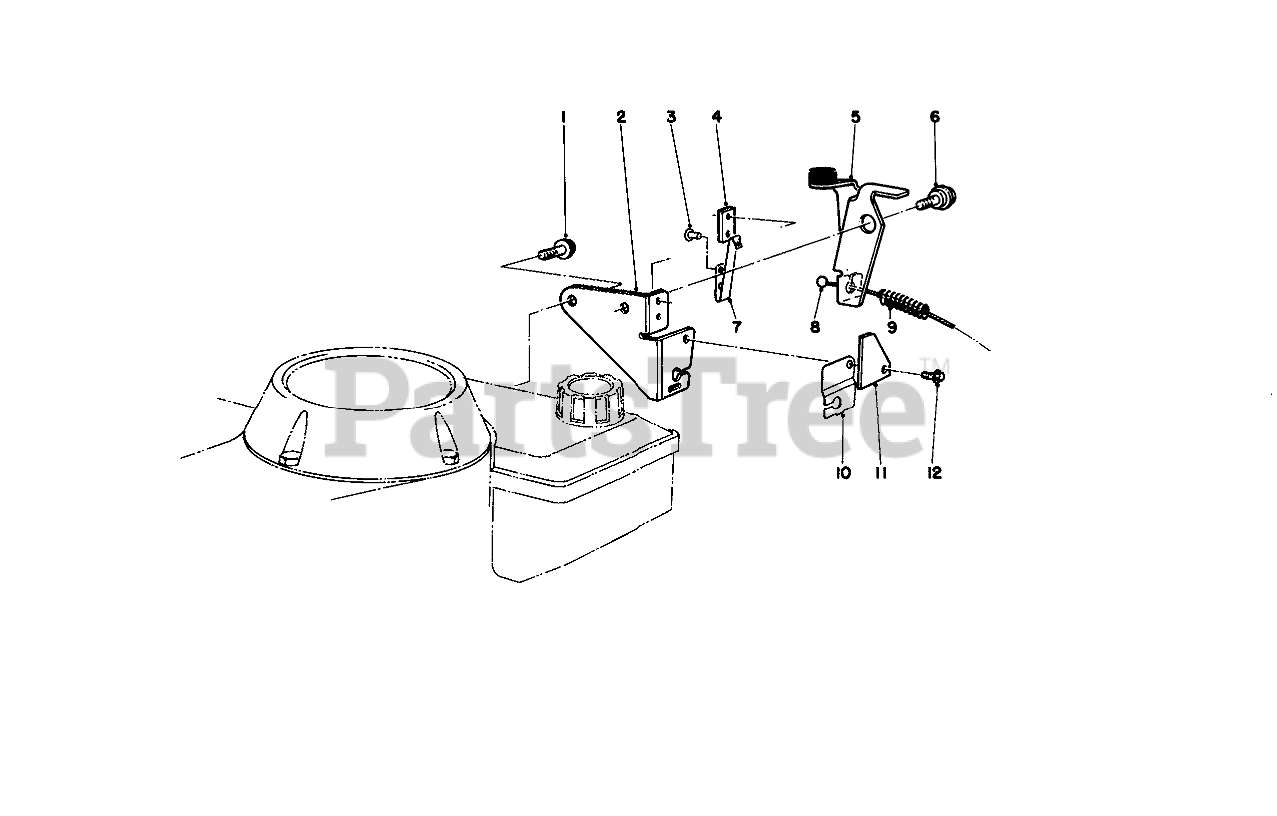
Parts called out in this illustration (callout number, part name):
1	THO FORM SCREW M6 X 1
2	Plate-Mounting
3	RIVET-PLASTIC
4	Strap-Insulation
5	BRAKE PLATE ASM
6	Screw-Shoulder
7	STRAP-GROUND
8	BRAKE CABLE
9	COMPRESSION SPRING
10	CABLE CLAMP
11	STOP-GROUND STRAP
12	SCREW
